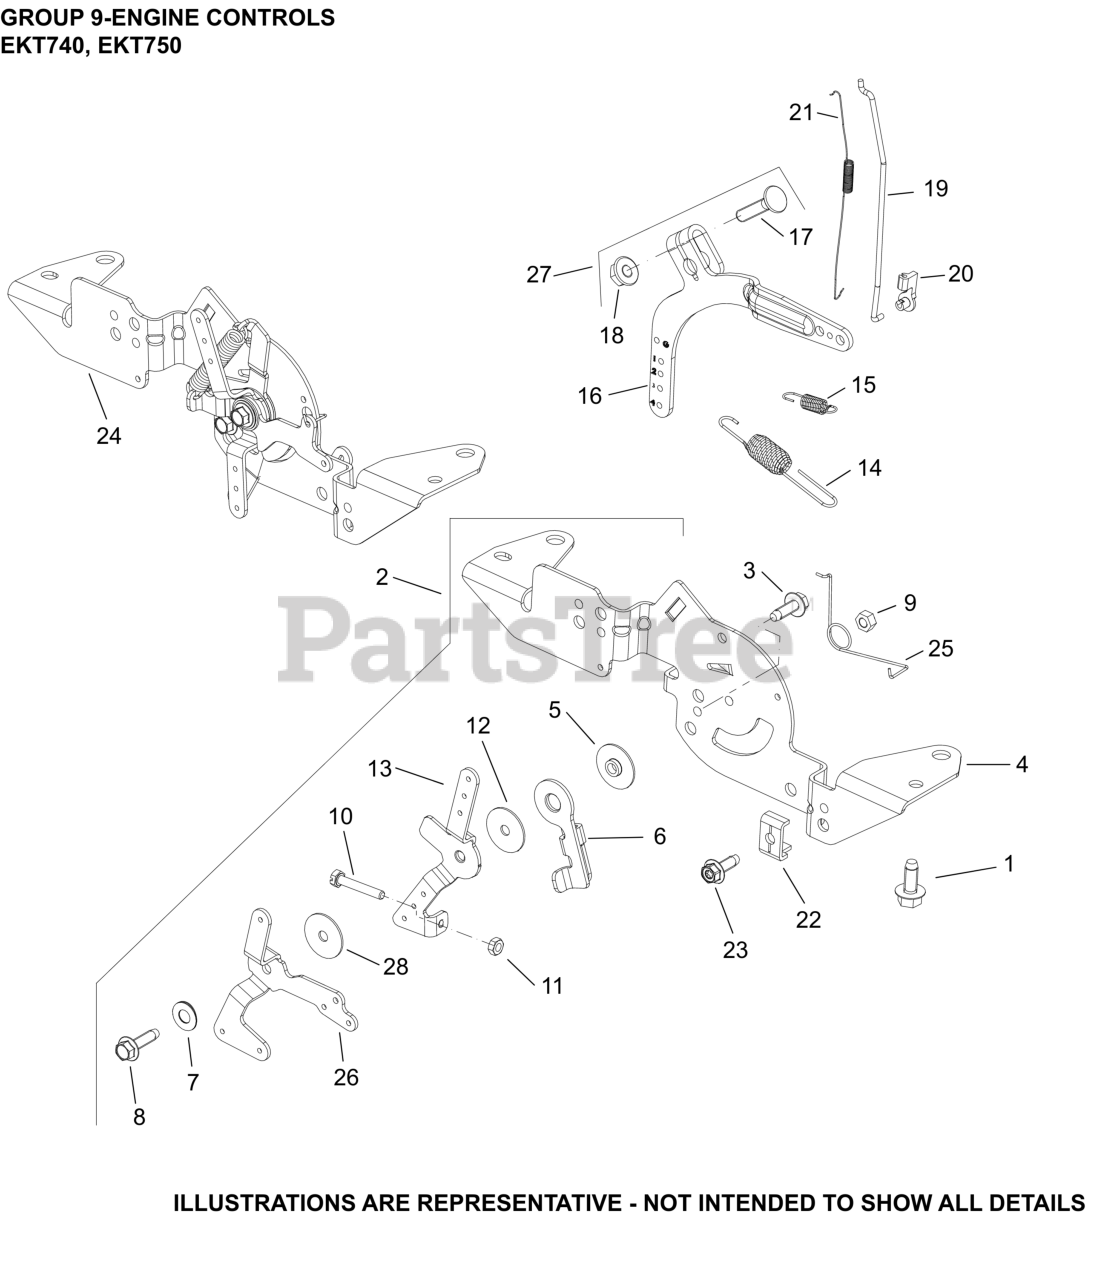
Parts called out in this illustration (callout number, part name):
1	SCREW, THREAD FORMING
2	CONTROL ASSEMBLY, DUAL WIRE
3	SCREW, THREAD FORMING
4	BRACKET, SPEED CONTROL
5	SPACER, CONTROL ASSEMBLY
6	LEVER, THROTTLE ACTUATOR
7	WASHER, SPRING 1/4"
8	SCREW, THD FRM-USE 25 086 473-S
9	NUT, LOCK M5X.8
10	SCREW, SLT HD CAP M4X0.7X25
11	NUT, M4X0.7
12	WASHER, FLAT 5 MM
13	LEVER, THROTTLE CONTROL
14	SPRING, GOVERNOR (ORANGE)
15	SPRING, GOVERNED IDLE
16	LEVER, GOVERNOR - (#2409069S)
17	BOLT, RD HD SQ NECK M6X1.0X25
18	NUT, FLG M6X1.0
19	LINKAGE, THROTTLE
20	BUSHING, THROTTLE LINKAGE
21	SPRING, LINKAGE
22	CLAMP, CABLE CABLE
23	SCREW, THREAD FORMING
25	SPRING, CHOKE RETURN
26	LEVER, CHOKE
27	LEVER, GOVERNOR ASSEMBLY
28	WASHER, FLAT 5.5 MM
